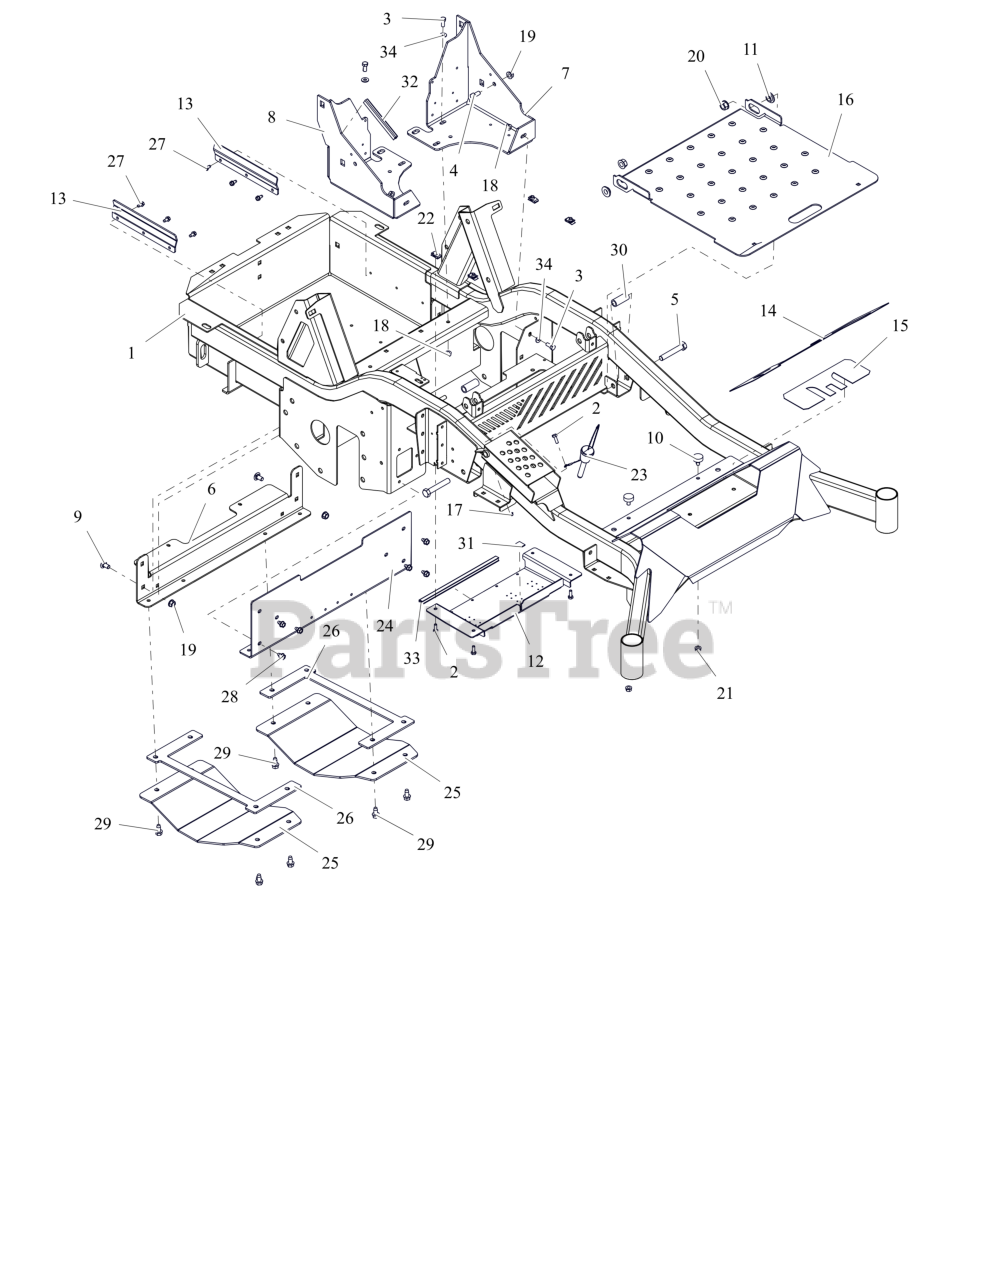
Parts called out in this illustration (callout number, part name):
1	WLDMT, MAIN FRAME PRO-TURN EV 60-A (ORANGE)
2	BLT, HEX .25-20X.75 G5 ZCC
3	BLT,HEX .31-18X.75 G5 ZCC
4	BLT,HEX .38-16X.75 G5 ZCC
5	BLT, HEX .50-13X3.00 G5 ZCC
6	BRKT, SKID PLATE MTG. (ORANGE)
7	BRKT, SUPPORT ROPS -LH (ORANGE)
8	BRKT, SUPPORT ROPS-RH (ORANGE)
9	BLT, RHSSN .38-16X.75 G5 ZCC
10	BUMPER, RUBBER
11	BSHG-FLG .515X.750X.395X1.120
12	COVER, BOTTOM ACCESS -OPEN (ORANGE)
13	DEFLECTOR, BATTERY -EV (ORANGE)
14	GRIP, FRONT
15	GRIP, TAPE FRONT
16	PANEL, ACCESS
17	NUT-LK-CTR-FLG .25-20 ZC120
18	NUT,LK-CTR-FLG .31-18 GF ZCC
19	NUT-LK-CTR-FLG .375-16 GF ZCC
20	NUT-LK-CTR-FLG .500-13 GG ZCC
21	NUT,SPNLK-FLG .31-18 G5 ZCC
22	NUT-RTNR .25-20X.56
23	PIN, MAGNETIC .50X2.50
24	PLATE, FRONT FRAME (ORANGE)
25	PLATE, SKID (BLACK)
26	PLATE, SKID TENSION (BLACK)
27	SCR-TAP .25-20X.50 HWH ZCC
28	SCR,TAP .312-18X.50 HWH TR ZCC
29	SCR,TAP .375-16X.75 HWH TR ZCC
30	SPACER, .515X.75X1.83
32	STRIP, COWL
33	STRIP, COWL
34	WSHR, FLT .312X.734X.065 ZCC
